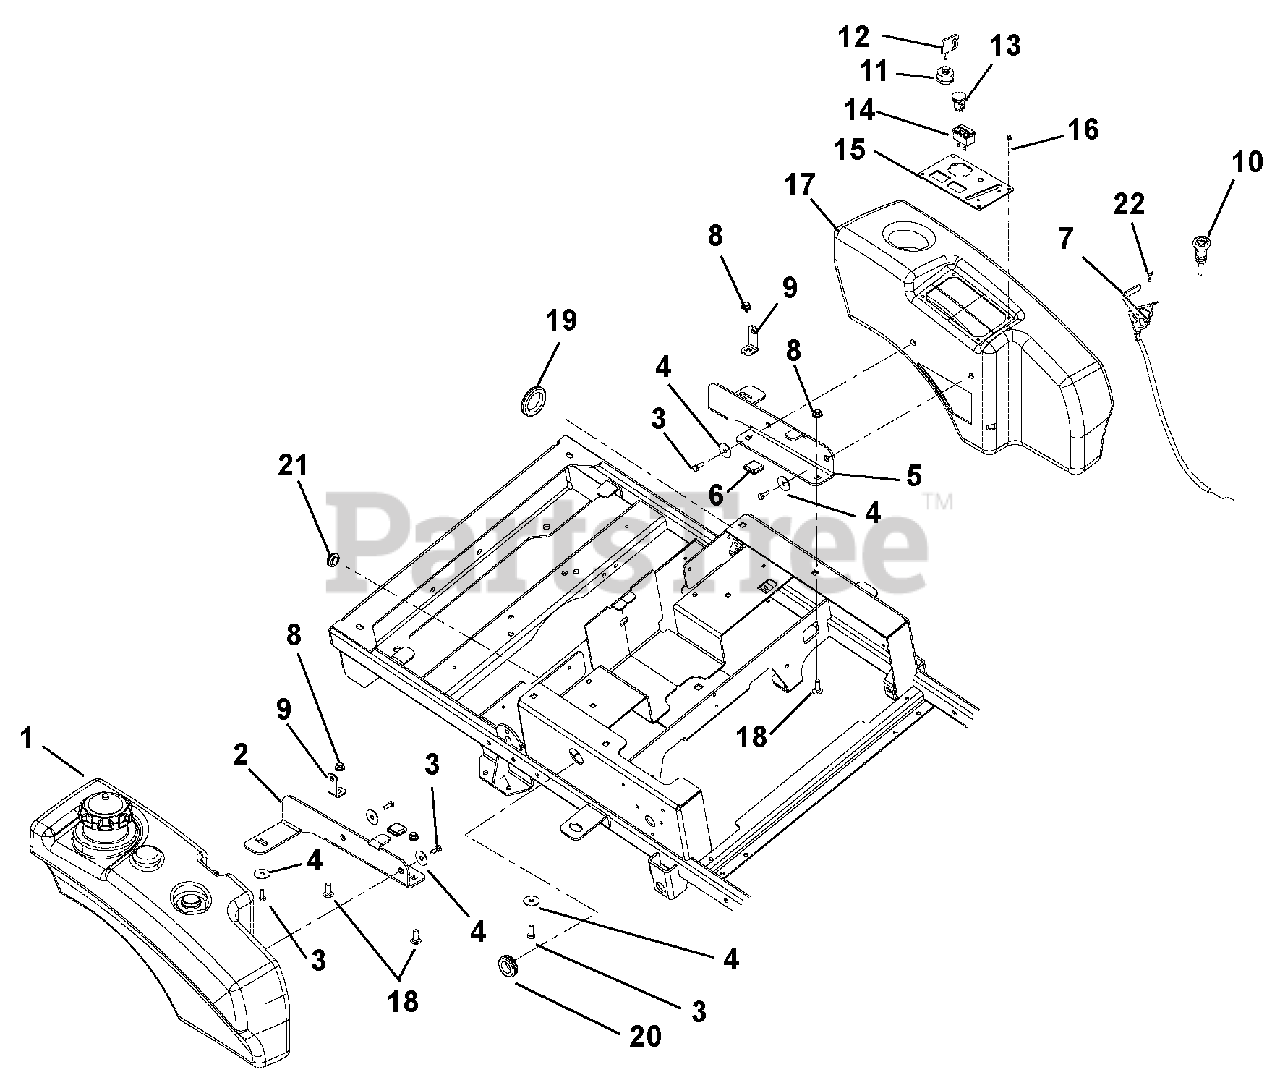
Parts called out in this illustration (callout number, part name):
1	TANK,ASSEMBLY XL CE
2	BRKT, RH REAR TANK MOUNT
3	BLT-SERHFWH .312-18X.50 YWZC
4	WSHR-FL-STL .347X1.254X.048YWZ
5	BRKT, LH REAR TANK MOUNT
6	GRIP, RUBBER (1.0X1.0X.187)BLK
7	CABLE-THROTTLE
8	@NUT-LK-NYL-FLG .38-16 YWZC
9	BRKT, HOOD PIVOT
10	CABLE, CHOKE
11	KEY SWITCH
12	KEY -W/CAP
13	SWITCH, CLUTCH
14	METER, HOUR W/MAINTENANCE
15	CONTROL PANEL
16	RIVET, PLASTIC .195 DIA.
17	FENDER, XL
18	@BLT-RDHDSQNK .38-16X1.00 G5YZ
19	GROMMET 1.70ID X 2.0OD
20	GROMMET 1.0ID X 1.38 OD
21	GROMMET,RUBBER 5/8 ID/1.13 OD
22	@SCR-TAP 10-24X.50 HWH TR YWZC
